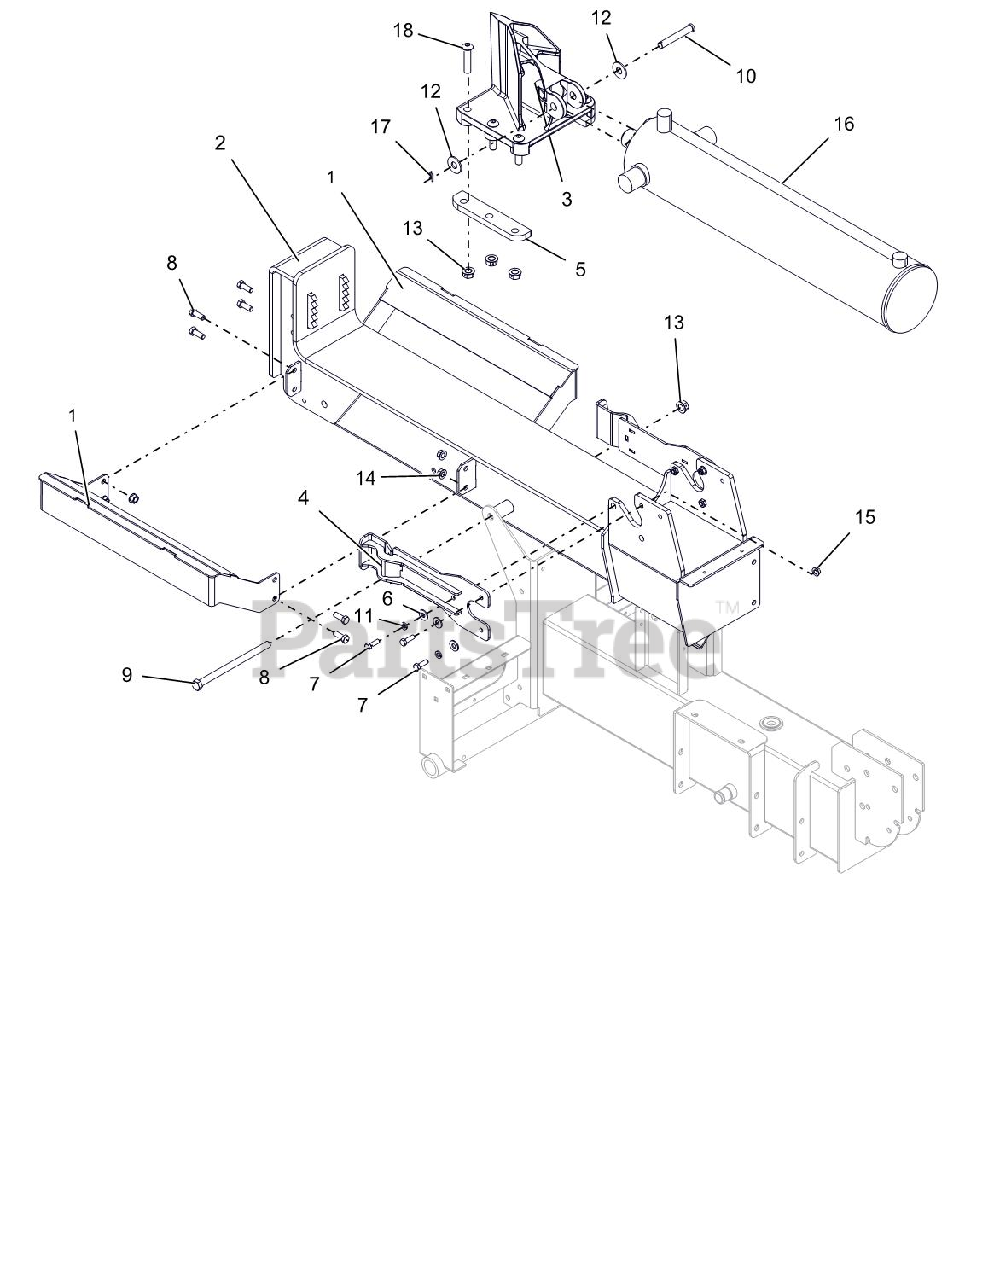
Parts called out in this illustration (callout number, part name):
1	WLDMT, CRADLE, LOG SPLITTER
2	WLDMT, BEAM - 27/34T SPLITTER
3	WEDGE-LOG SPLITTER-MACHINED
4	WLDMT, PLATE - STRIPPER
5	RETAINER-WEDGE
6	@WSHR-FL-STL.38X.875X.083 YWZC
7	@BLT-HEX .31-18X1.00 GR5 YWZC
8	@BLT-HEX .38-16X1.00 GR5 YWZC
9	@BLT-HEX .50-13X7.50 GR5 YWZC
10	PIN-CLEVIS .500 X 3.250
11	WSHR-LK .312X.097 HVY YWZC
12	@WSHR-FL-STL.563X1.38X.109YWZC
13	NUT-LK-CTR-FLG .50-13 YWZC
14	@NUT-LK-TOP-FLG .38-16 YWZC
15	@NUT-LK-TOP-FLG .31-18 YWZC
16	CYLINDER, 5' W/DECALS
17	CLIP, SPRING
18	SCR-SKH .500-13X2.250 BTH YZ
